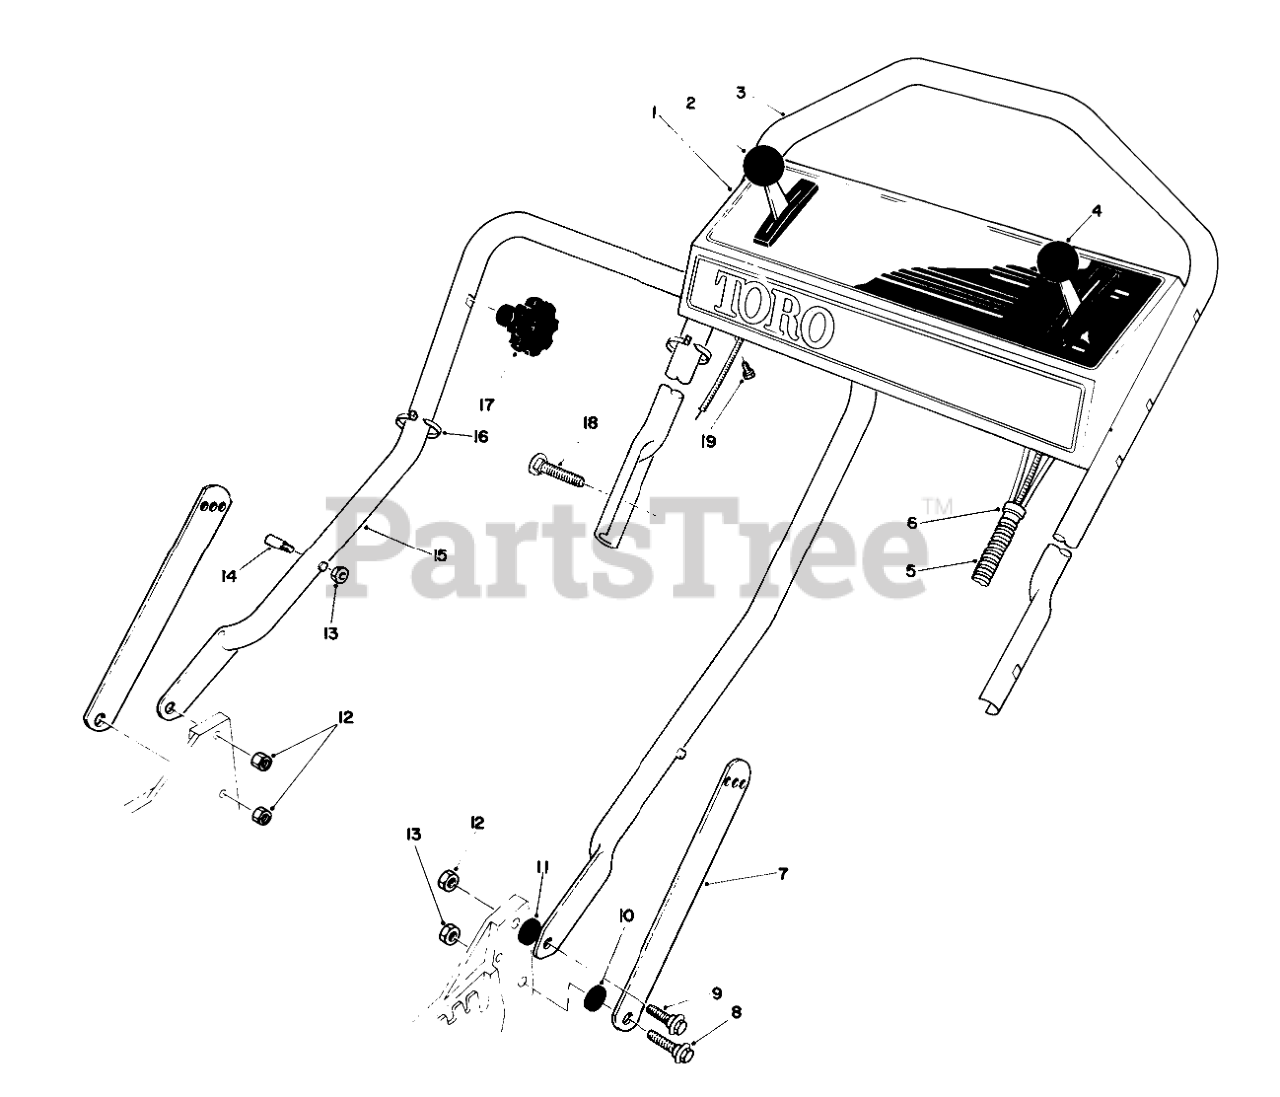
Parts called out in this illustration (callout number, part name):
1	Panel-Control
2	GROUND SPEED CONTROL
3	Handle-Upper
4	THROTTLE CONT-SERVICE
5	CONTROL CABLE COVER
6	FITTING-RING
7	Handle Latch
8	SCREW-SHOULDER
9	SCREW-SHOULDER
10	SPACER
11	SPACER
12	NUT-LOCK, NI
13	NUT-LOCK, NI
14	HANDLE PIN
15	LOWER HANDLE ASM
16	TIE-CABLE
18	5/16-18 X 2 HNDLE SCREW
19	SCREW-HWHTF
